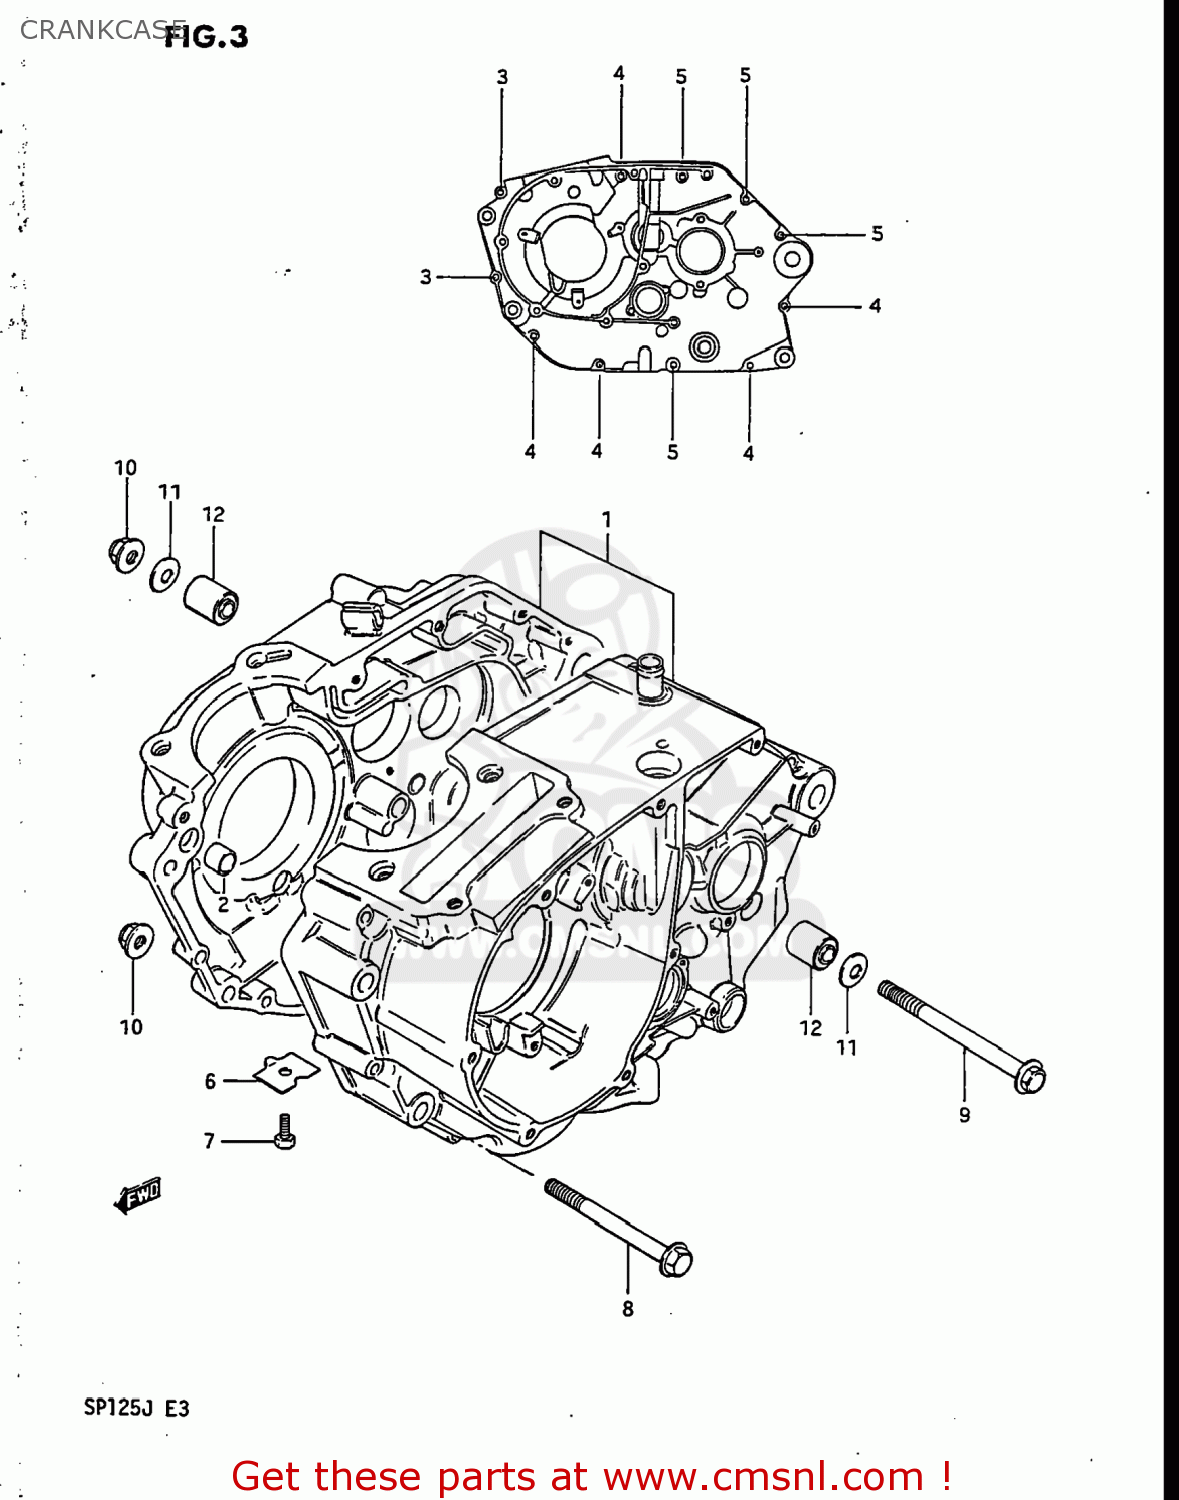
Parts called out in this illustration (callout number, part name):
1	CRANKCASE SET
2	PIN
3	BOLT
4	BOLT (6X60)
5	BOLT (6X75)
6	PLATE,OIL GALLERY PLUG
7	BOLT
8	BOLT(8X80)
9	BOLT(8X115)
10	NUT
11	WASHER
12	BUSH(8.4X18X16)
